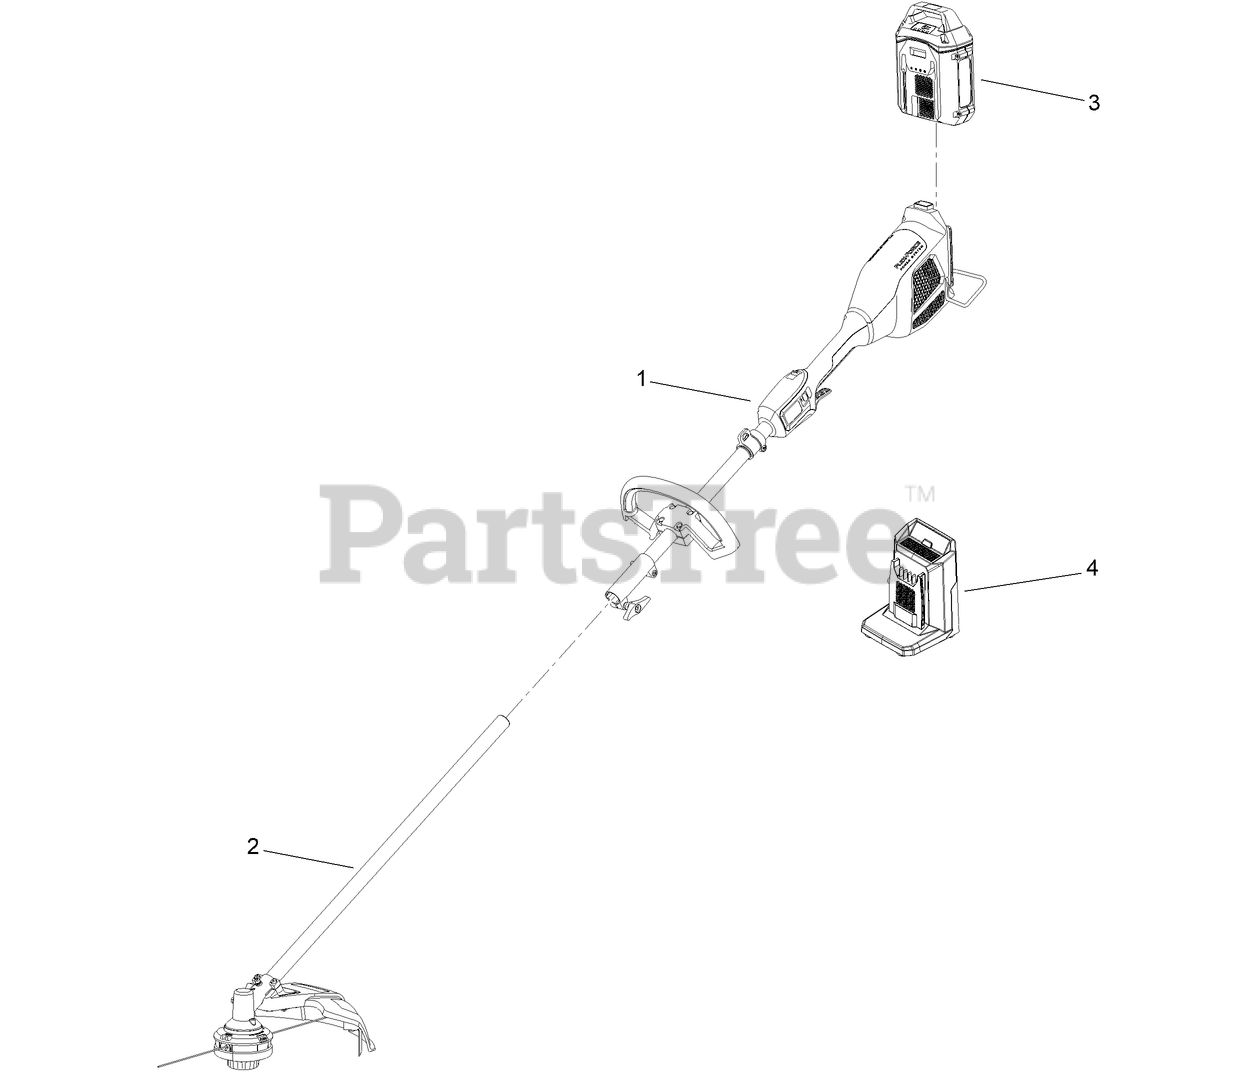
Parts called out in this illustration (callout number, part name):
1	POWER HEAD
2	TRIMMER ATTACHMENT
3	BATTERY-LI ION, 60V 2.5 AH
4	CHARGER-BATTERY, 60V 2 AMP
